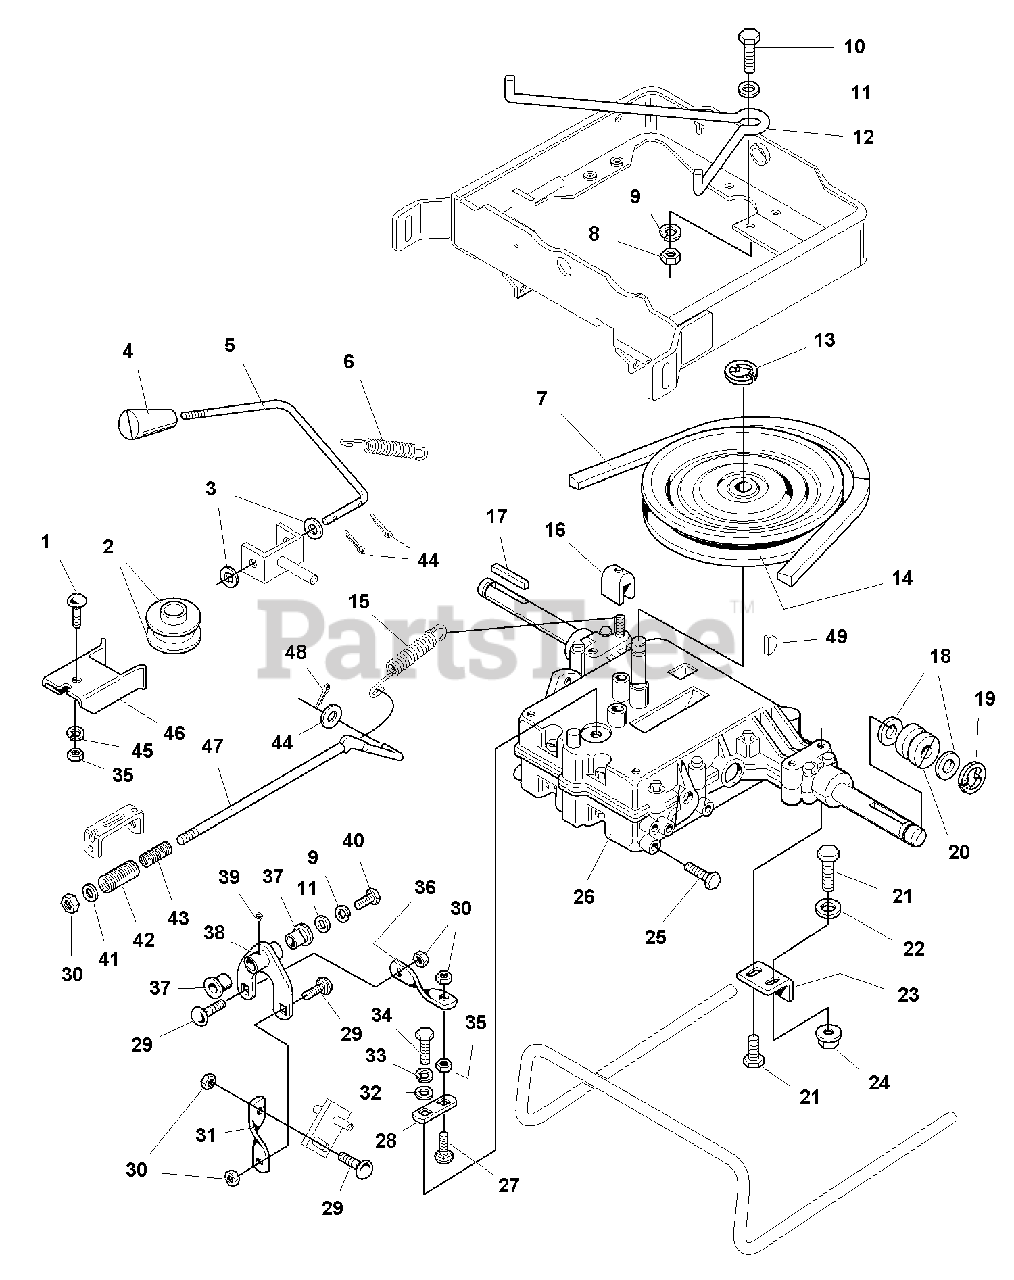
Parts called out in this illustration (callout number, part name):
1	CARRIAGE BOLT, 5/16-18 x 3/4
6	SPRING, Extension
8	NUT, Hex 3/8-16
9	LOCKWASHER, 3/8
10	CAPSCREW, Hex Head, 3/8-16 x 1-1/4
11	WASHER
12	GUIDE, Belt
13	RING, Shaft
14	PULLEY & HUB ASSEMBLY
15	SPRING, Extension
17	KEY
19	RING, Shaft
21	SCREW, Hex Washer Head Taptite, 5/16-18 x 2-1/2
22	WASHER
23	ANCHOR, Torsion Bar
24	NUT, Hex Head Whiz Lock, 5/16-18
25	SCREW, Hex Washer Head Taptite, 5/16-18 x 5/8
26	TRANSMISSION ASSEMBLY
27	CARRIAGE BOLT, 5/16-18 x 1-1/2
28	LEVER, Shift
29	CARRIAGE BOLT, 5/16-18 x 1-1/4
30	NUT, Hex Lock, 5/16-18
31	LINK, Shift Upper
32	WASHER
33	LOCKWASHER, 1/4
34	CAPSCREW, Hex Head, 1/4-28 x 5/8
35	NUT, Hex, 5/16-18
36	LINK, Shift, Lower
38	BELLCRANK ASSEMBLY w/Bushings (Incl. Ref ??)
39	FITTING, Grease
40	CAPSCREW, Hex Head, 3/8-16 x 3/4
42	SPRING-Compression
43	SPRING-Compression
44	PIN, Cotter
45	LOCKWASHER, 5/16
46	GUARD, Belt
48	PIN, Cotter
49	KEY, Woodruff #9
